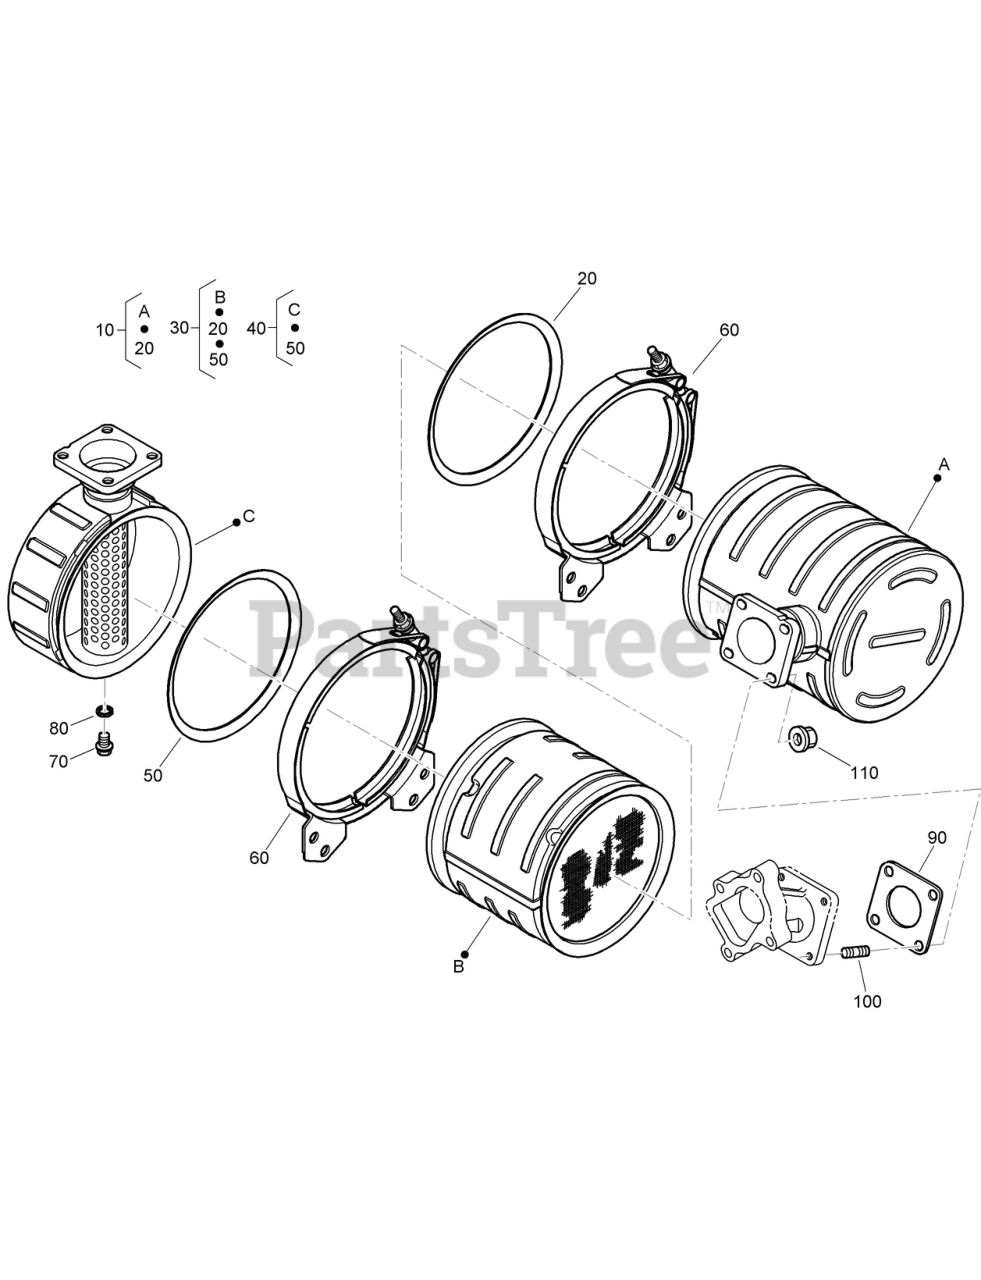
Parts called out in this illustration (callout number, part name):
10	DOC1 CATALYST KIT
20	GASKET-D P F
30	DOC2 CATALYST KIT
40	BODY KIT
50	GASKET-D P F
60	BRACKET-V BAND, D P F
70	BOLT-FLANGE
80	GASKET
90	GASKET-MUFFLER
100	BOLT-STUD
110	NUT-FLANGE
